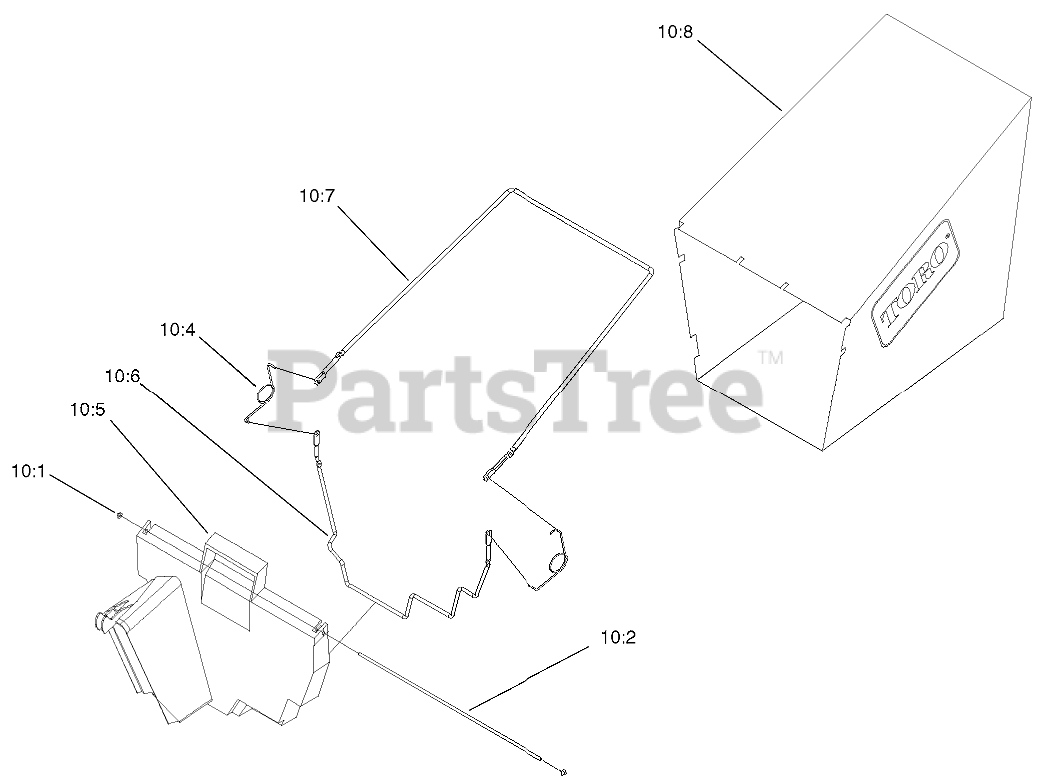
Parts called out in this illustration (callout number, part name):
10	GRASS BAG ASM
10:1	NUT-PUSH
10:2	HINGE-DOOR, BAG
10:4	SPRING
10:5	DOOR-BAG
10:6	FRAME-BAG
10:7	FRAME-BAG, UPPER
10:8	BAG-GRASS
